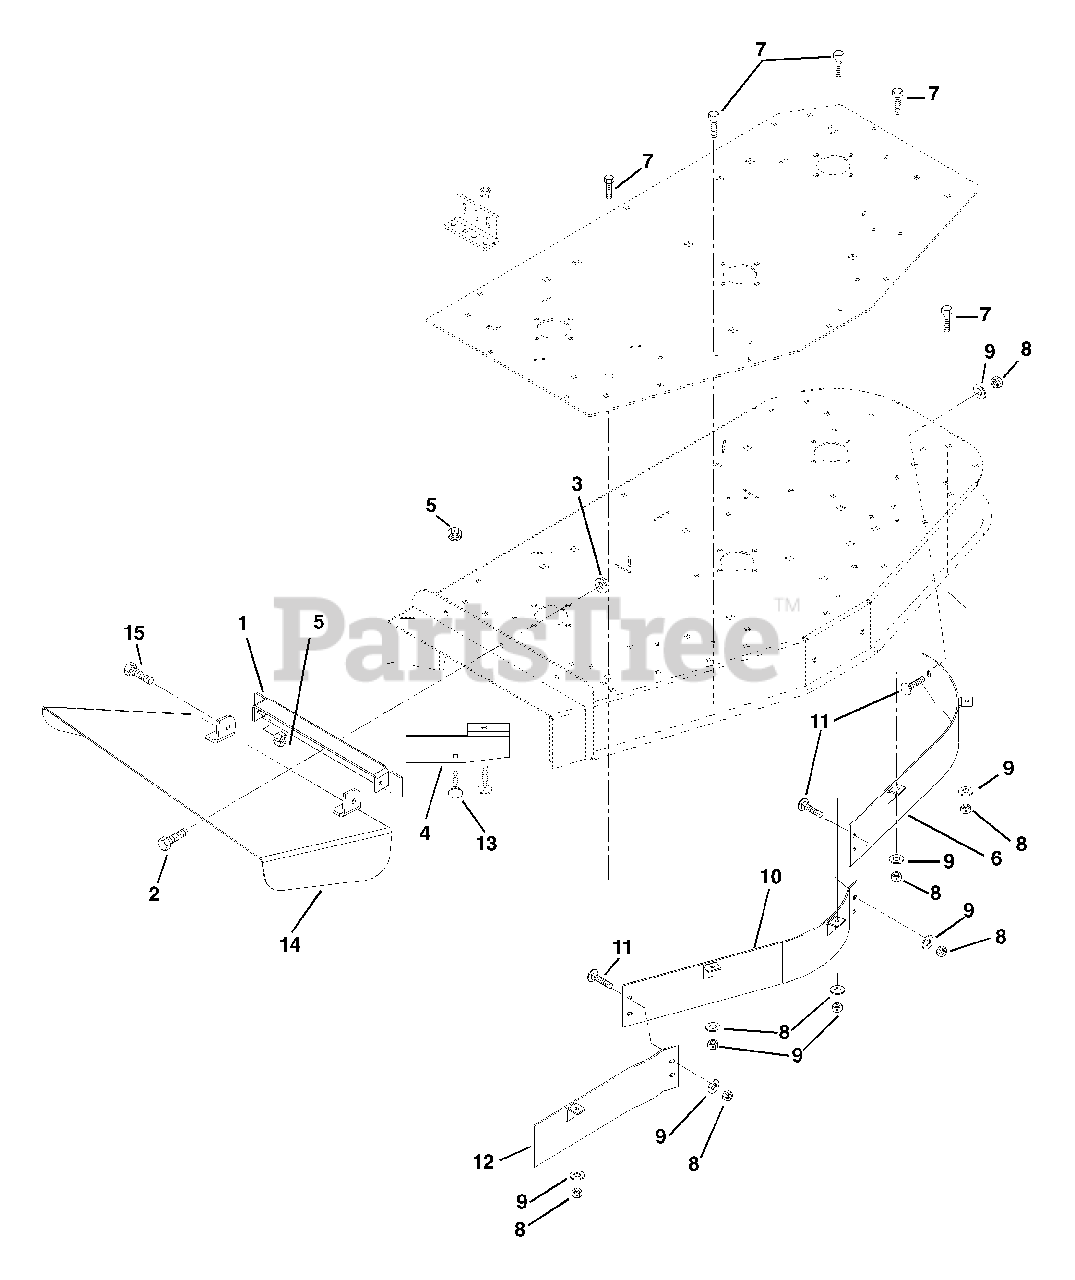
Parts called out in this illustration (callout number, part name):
1	Weldment, Discharge Chute Bracket
2	Bolt-Hex .38 - 16 x 1.00 Grade 5
3	Nut-Locking-Flange .38 - 16
4	Deflector
5	Nut-Locking-Center .38 - 16
6	Weldment, 50" Left Hand Baffle-Upper
7	Bolt-Hex .31 - 18 x 1.00 Grade 5
8	Nut-Locking-Nylon .31 - 18
9	Washer-Flat-Steel .312 x .734 x .065
10	Weldment, 50" Center Baffle-Up
11	Bolt-Round Head Square Neck .31 - 18 x .75 Grade 5
12	Weldment, 50" Right Hand Baffle-Upper
13	Bolt-Round Head Square Neck .38 - 16 x 1.00 Grade 2
14	Weldment, Discharge Chute 50"
15	Bolt-Hex .38 - 16 x 1.00 Grade 5
16	50" Discharge Cover
17	50" Mulch Kit
